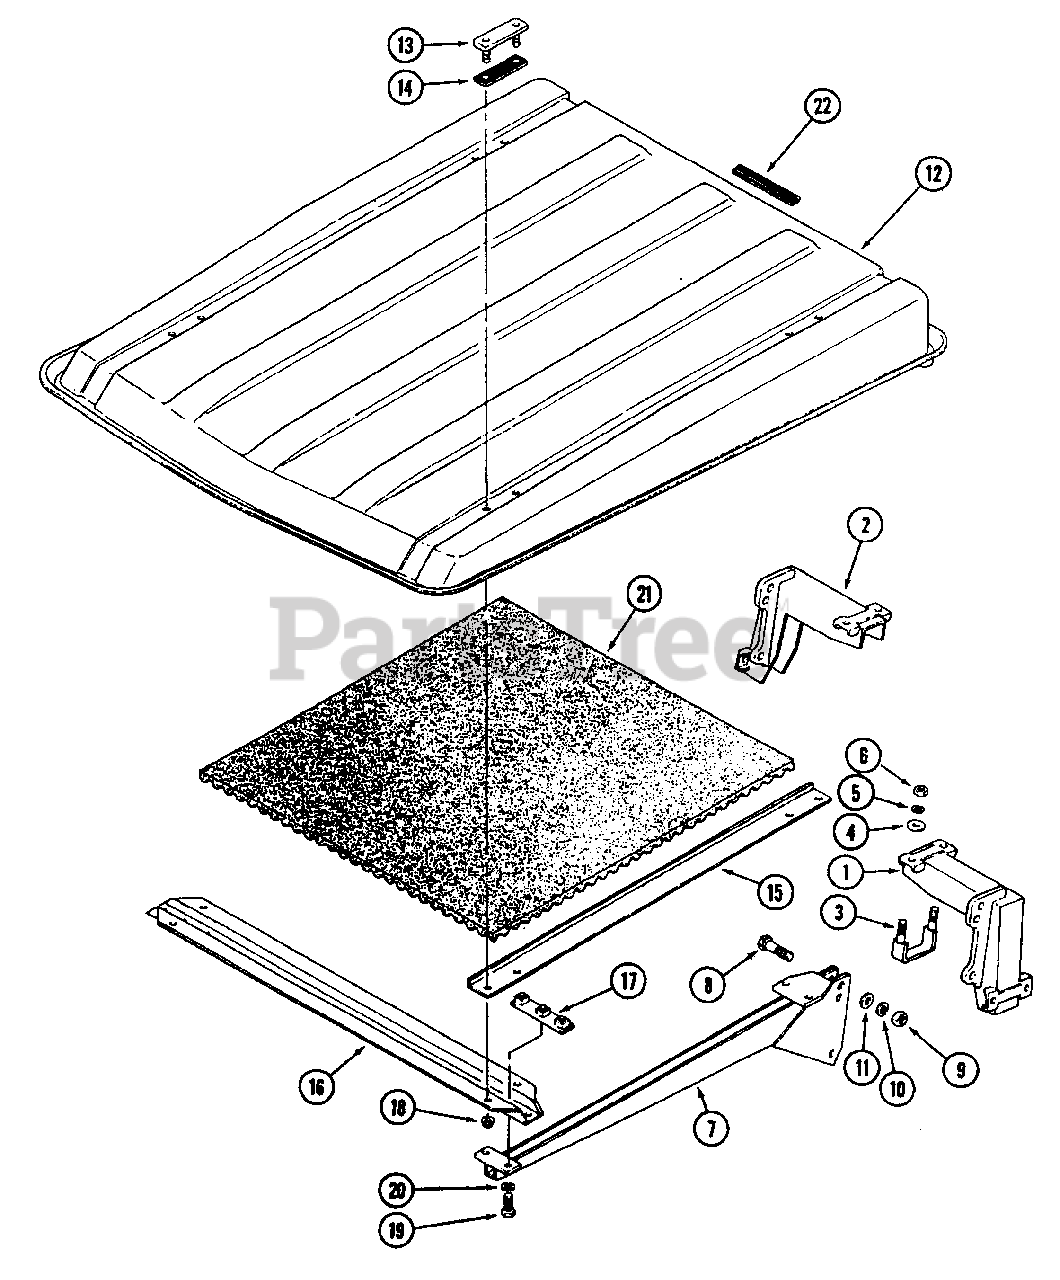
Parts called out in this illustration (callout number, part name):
1	Support L.H.
2	Support R.H.
3	U-Bolt
4	Washer
5	Washer
6	Nut
7	Frame
8	Bolt
9	Nut
10	Washer
11	Washer
12	Roof Ass'y.
13	Clamp, Roof
14	Packing
15	Plate
16	Frame
17	Clamp
18	Nut
19	Bolt
20	Washer
21	Cuthion
22	Trim
